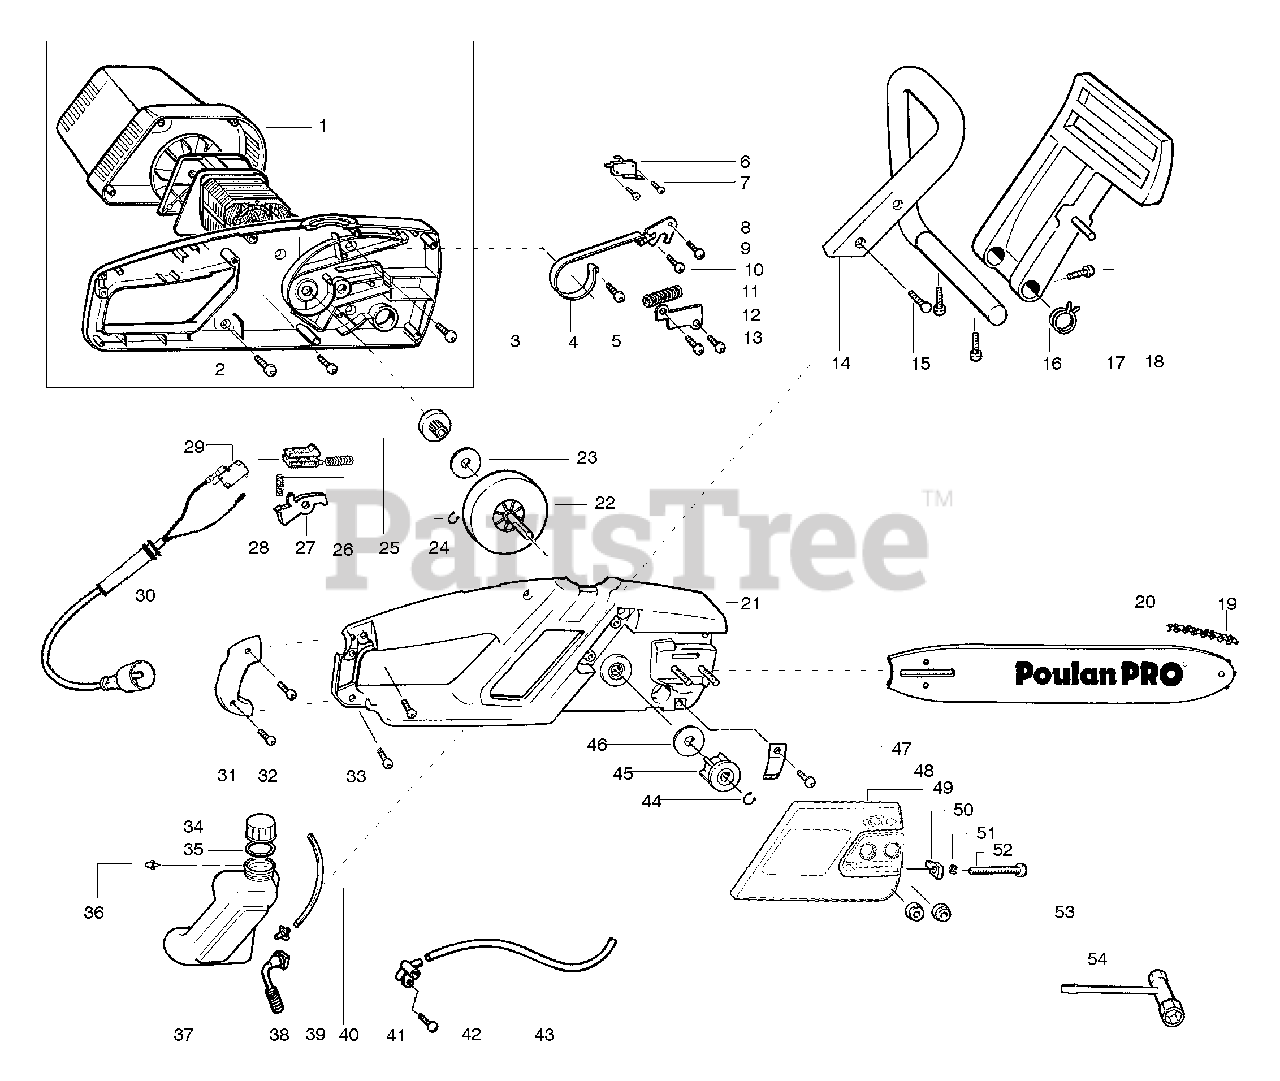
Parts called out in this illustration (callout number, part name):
1	Motor Cover
3	Housing/Motor Ass'y.
4	Brake Band
6	Switch-Chain Brake
7	Screw
8	Front/Rear Link Ass'y.
9	Screw-Brake Pivot
10	Screw
11	Spring-Brake
12	Cover Spring
14	Front Handle
16	Spring-Handguard
18	Handguard
19	Chain 18"
21	Housing Cover
22	Gear Drive
23	Washer-Thrust
24	Ring-Retainer
26	Spring-Trigger
28	Lockout Button
29	Switch-Momentary
30	Assy-Wire Harness
31	Cover-Access
34	Oil Cap
35	O-Ring (Oil Cap)
36	Check Valve (Duckbill)
37	Oil Tank Ass'y.
38	Oil Pickup Ass'y.
39	Oil Pickup Fitting
40	Inlet Line
41	Oil Pump Ass'y.
43	Outlet Line
44	Ring-Retainer
45	Sprocket (3/8 Pitch)
46	Washer-Sprocket
47	Chain Catcher
49	Bar Clamp
50	Pin-Bar Adjust
51	Retainer-Bar Adjust
52	Screw-Bar Adjust
53	Nut-Bar Mounting
54	Bar Wrench
